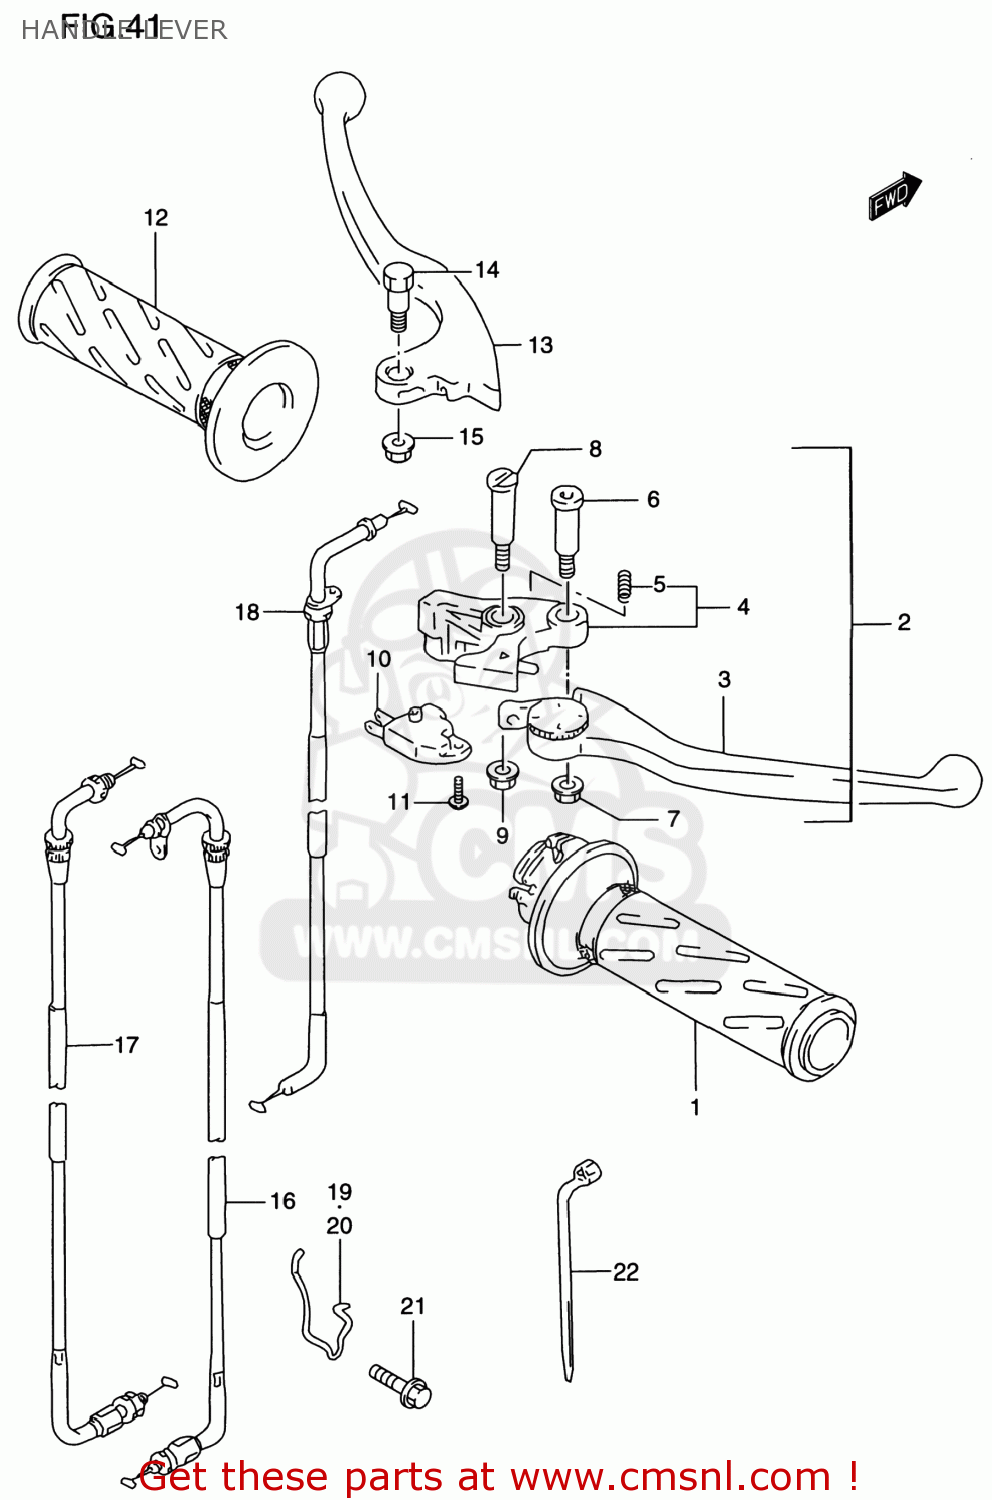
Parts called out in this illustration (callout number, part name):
1	GRIP,THROTTLE
2	LEVER ASSY,BRAKE
3	LEVER,ADJUST
4	KNOCKER
5	SPRING
6	BOLT,LEVER
7	NUT
8	BOLT,LEVER PIVOT
9	NUT
10	SWITCH ASSEMBLY,STOP
11	SCREW
12	GRIP,LEFT
13	LEVER,CLUTCH (SILVER)
14	BOLT,LEVER
15	NUT
16	CABLE ASSY,THROTTLE NO.1
17	CABLE ASSY,THROTTLE NO.2
18	CABLE,STARTER
19	GUIDE,CABLE NO.1
20	GUIDE,CABLE NO.2
21	BOLT
22	CLAMP(L:125)
